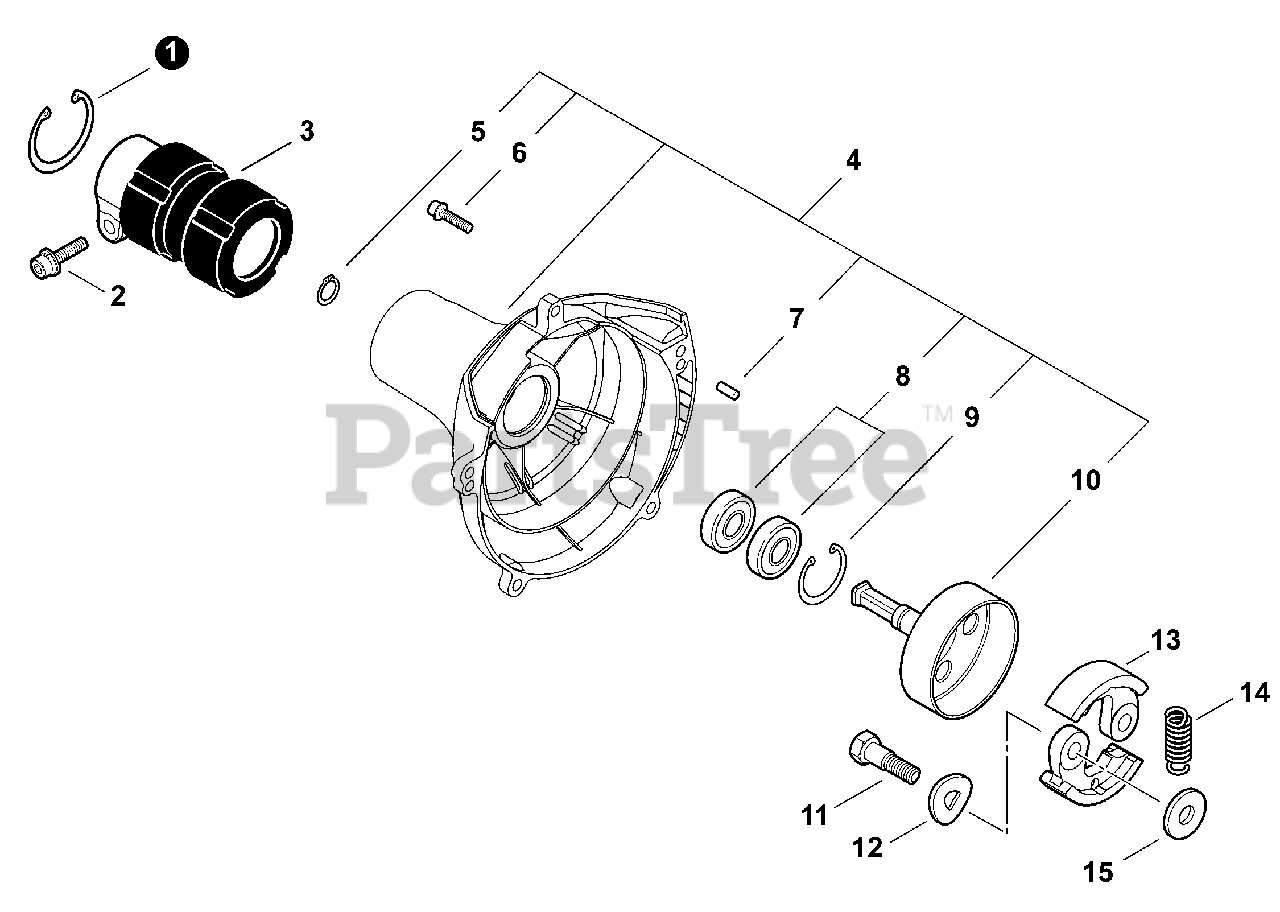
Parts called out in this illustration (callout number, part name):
1	CIRCLIP 42
2	BOLT, H.S. 5×28
3	HOLDER, MAIN PIPE
4	FAN CASE ASY
5	RING, RETAINING - 12
6	SCREW - 5×20
7	PIN, DOWEL
8	BEARING, BALL - 6001
9	RING, RETAINING - 28
10	DRUM, CLUTCH
11	BOLT, CLUTCH
12	WASHER - SPRING
13	SHOE, CLUTCH
14	SPRING, CLUTCH
15	WASHER - 6
